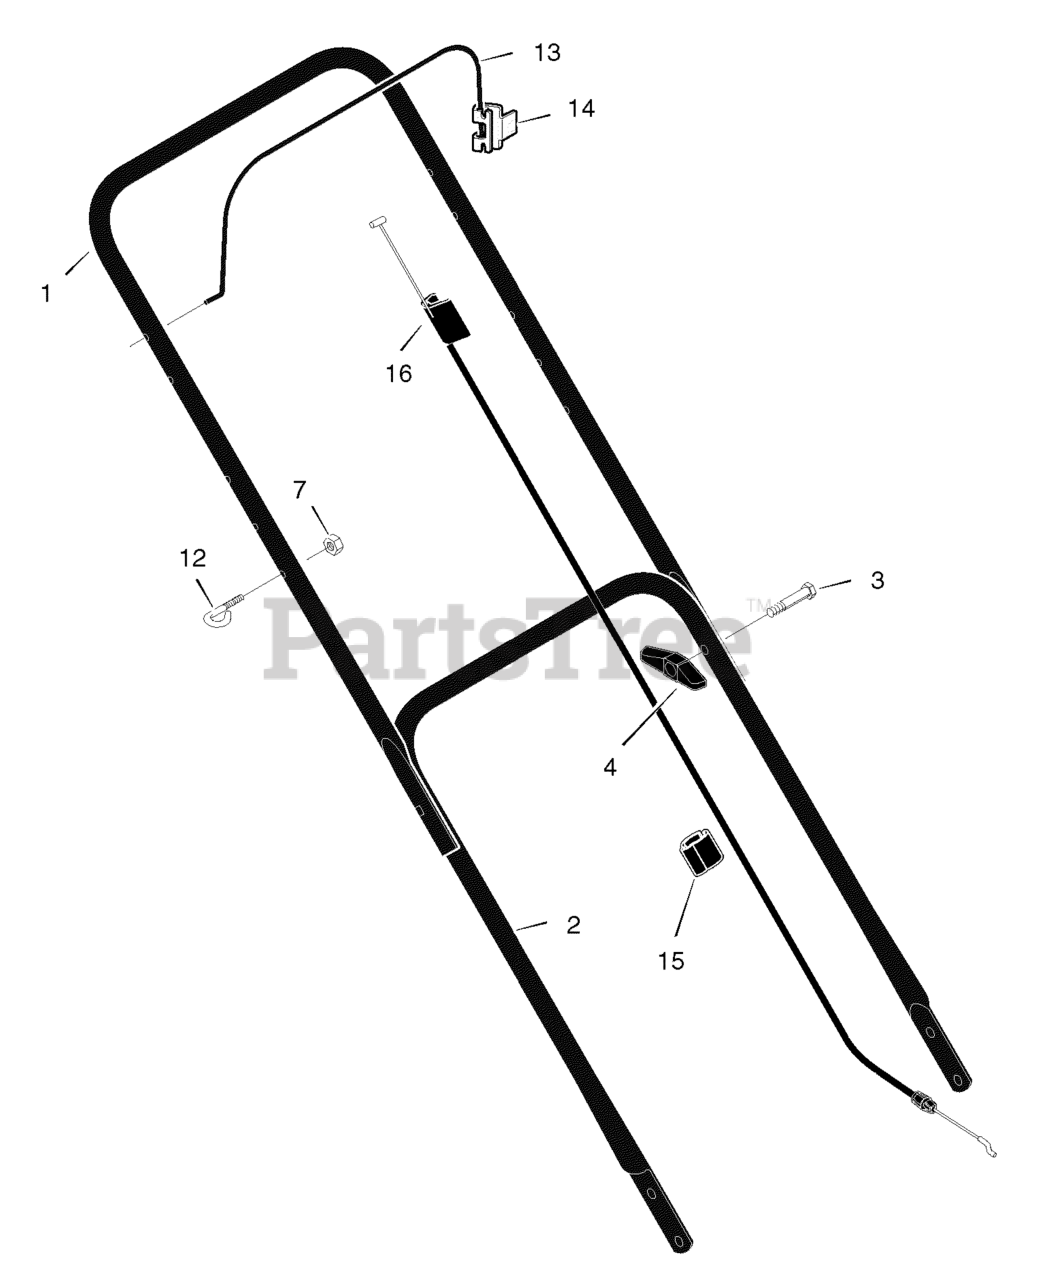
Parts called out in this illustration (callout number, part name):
1	Handle, Upper (Black)
2	Handle, Lower (Black)
4	Knob, Plastic
7	Locknut
12	Guide, Rope
13	Engine Stop Lever
14	Bracket, Stop Lever
15	Clamp, Cable
16	Engine Stop Cable *
